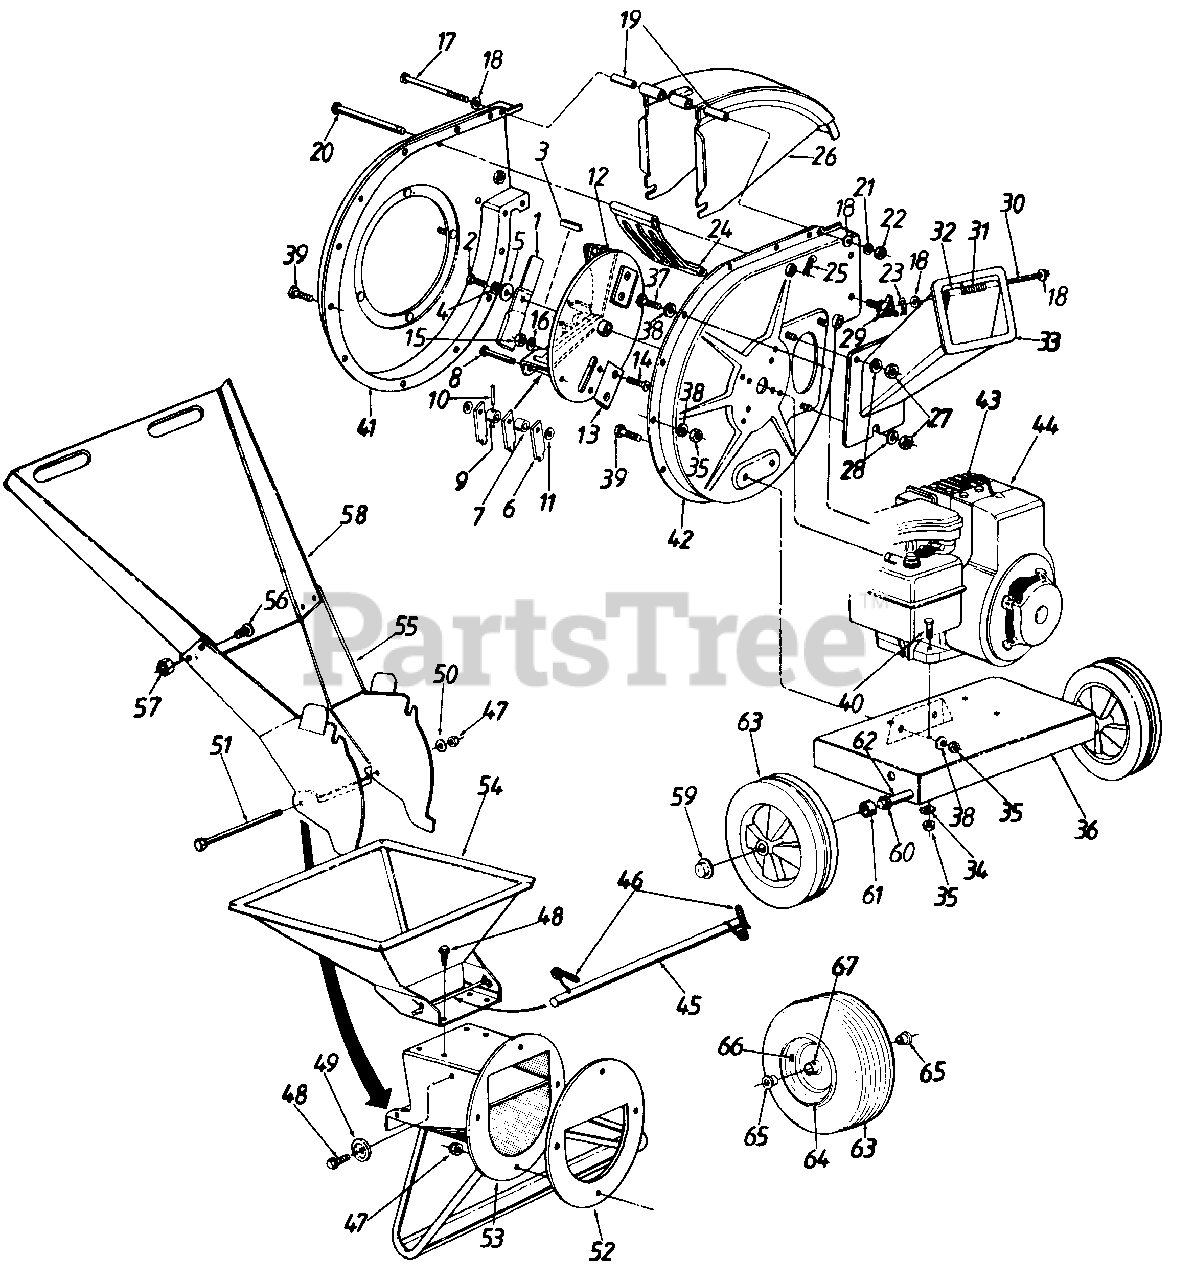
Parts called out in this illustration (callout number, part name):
3	Sq. Key 1/4 x 2.0" Lg.
4	L-Wash. 3/8" I.D. H.D.
5	Fl-Wash. .406" I.D. x 1.25" O.D. Hdn.
6	Flail
7	Flail Spacer
8	Clevis Pin .496" Dia.
9	Flail Spacer w/.160" Dia. Hole
10	Spring Roll Pin 1.12" Lg.
11	Fl-Wash. .531" I.D. x .94" O.D.
12	Impeller Ass'y.
13	Chipper Blade
14	Flat Hd. Scr. 5/16-24 x .75" Lg.
15	Hex Top L-Nut 5/16-24 (Grade 5)
16	L-Wash. 5/16" I.D.*
17	Hex Bolt 1/4-20 x 4.0" Lg.*
18	Fl-Wash. .344" I.D. x 875" O.D.
19	Chute Hinge Spacer 1.66" Lg.
20	Clevis Pin .5" Dia. x 4.62" Lg.
21	L-Wash. 1/4" I.D.*
22	Hex Nut 1/4-20 Thd.*
23	Cap Speed Nut 1/4" Rod
25	Internal Cotter Pin 818n Dia.
27	Hex Nut 5/16-18 Thd. (Grade 5)
28	Bell-Wash. .345" I.D. x .88"
29	Hand Knob
30	Chipper Door Rod
31	Torsion Spring 1.14" Lg.
35	Hex Nut 5/16-18 Thd. (Grade 5)
36	N/638 Shredder Frame
37	Hex Bolt 5/16-24 x .75" Lg.
38	L-Wash. 5/16" I.D.
39	Hex Bolt 5/16-18 x .75" Lg. (Grade 5)
40	Hex Bolt 5/16-18 x l.75" Lg.
43	Spark Plug Boot
44	Engine
45	Release Bar
46	Torsion Spring 1.06" Lg.
47	Elastic Lock Nut 5/16-18 Thd.
48	Hex Wash. Hd. Self-Tap Scr. 5/16-18 x 75n Lg.
49	Stop Washer
50	Fl-Wash. 5/16" I.D.
51	Hex Bolt 5/16-18 x 8.38" Lg.
52	Back-Up Plate
53	Inlet Guide Ass'y.
57	Hex L-Nut 1/4-20 Thd.
60	Fl-Wash. 54" I.D. x 1.24"
61	Spacer .54" I.D. x .38" Lg.
62	Shredder Axle
63	Wheel Ass'y. Comp.
64	Rim Only
65	Flange bearing .632" I.D.
66	Air Valve
67	Grease Fitting
